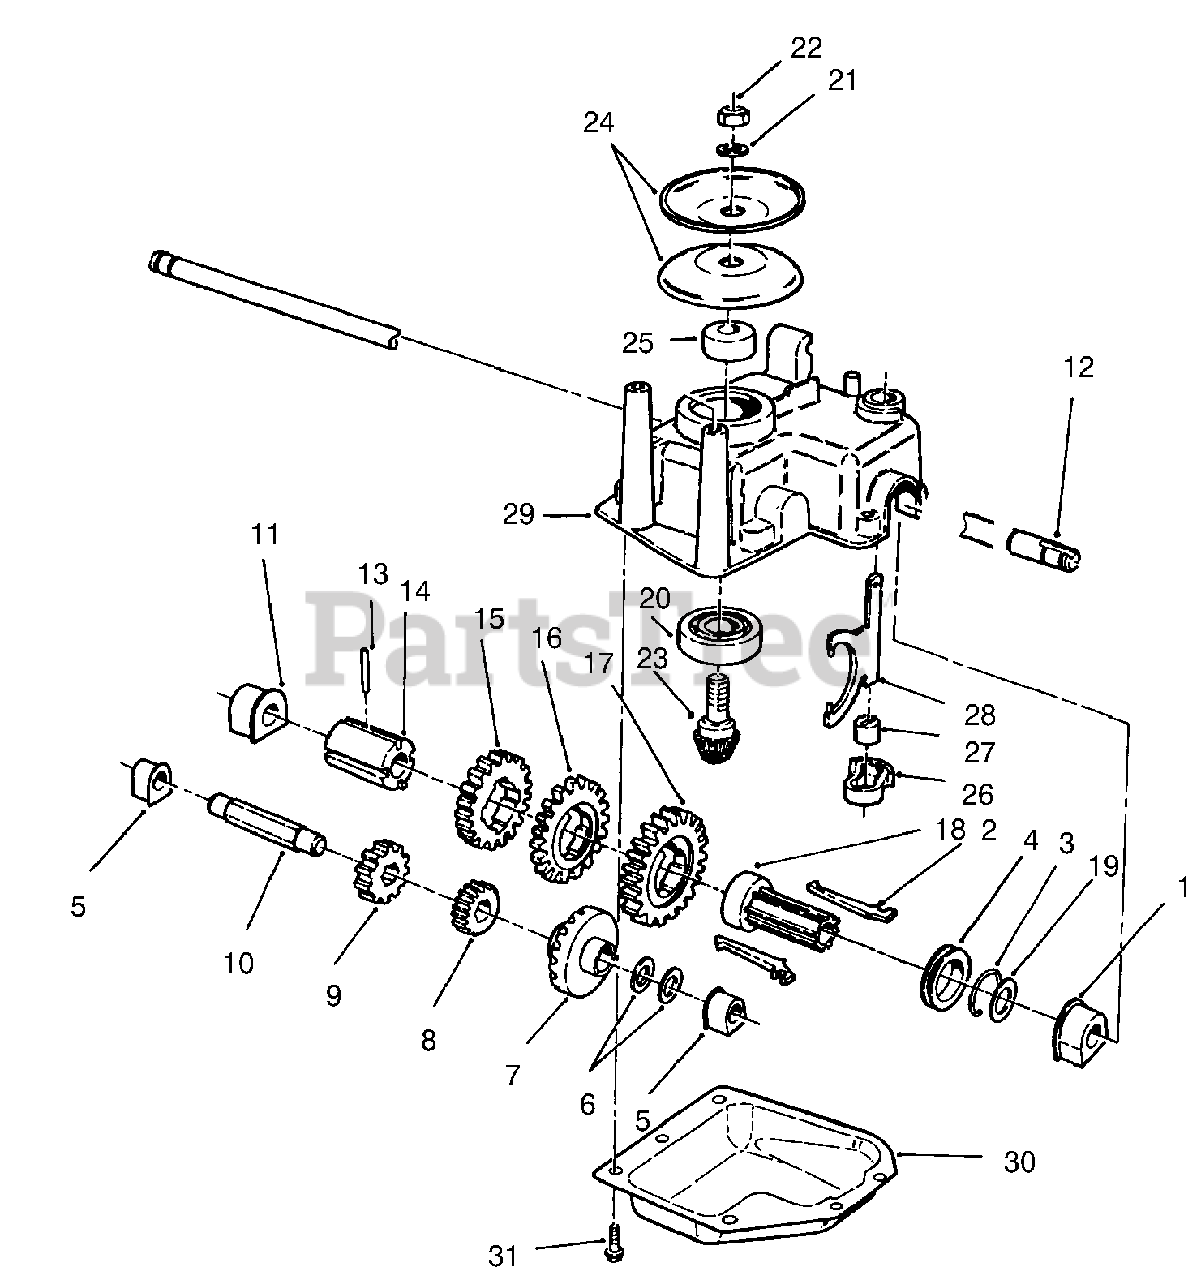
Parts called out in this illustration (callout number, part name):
1	Bushing-Output Shaft
2	Key-Shift
3	Clip-Spring
4	Collar-Shift
6	Washer-Thrust
7	Pinion-15T
8	Pinion-20T
9	Pinion-25T
10	Shaft-Intermediate
11	Bushing-Output
12	Shaft-Output
13	Pin-Spirol
14	Sleeve-Gear
15	Gear-39T
16	Gear-44T
17	Gear-49T
18	Sleeve-Shift Key
19	Washer-Thrust
20	Bearing-Ball
21	Washer-Flat
22	Nut-Lock
23	Pinion-Bevel
24	Pulley-Half
25	Spacer-Pulley
26	Retainer-Shift-Fork
27	Bushing-Yoke
28	Yoke-Shift
29	Gearcase-Upper
30	Cover-Gearcase
31	Screw-HH
